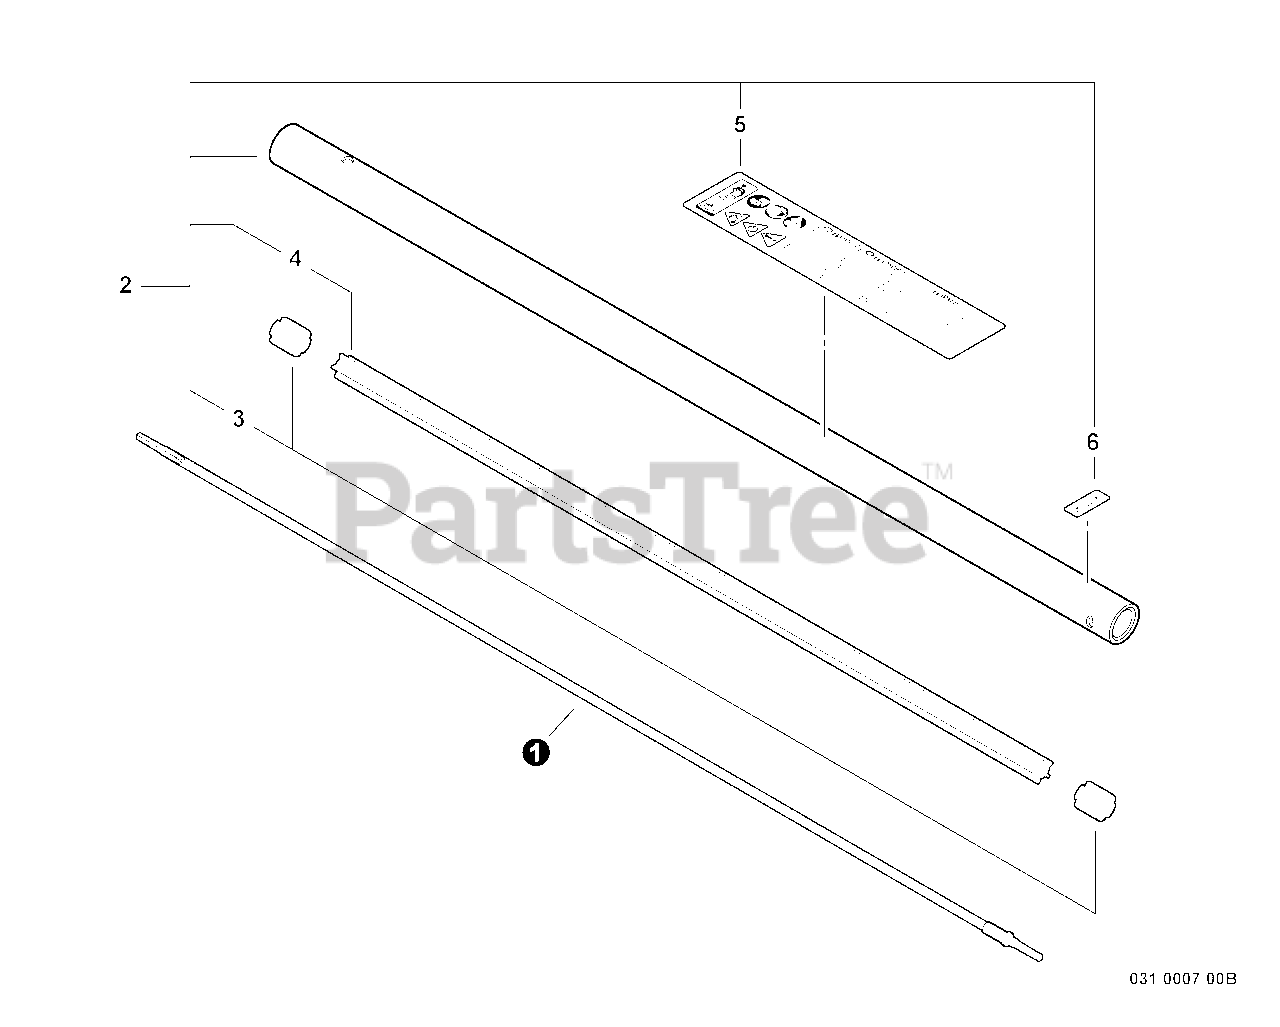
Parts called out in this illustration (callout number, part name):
1	DRIVESHAFT - FLEXIBLE
2	MAIN PIPE ASSY
4	LINER - FLEXIBLE
5	LABEL, CAUTION
6	LABEL - ALIGNMENT
